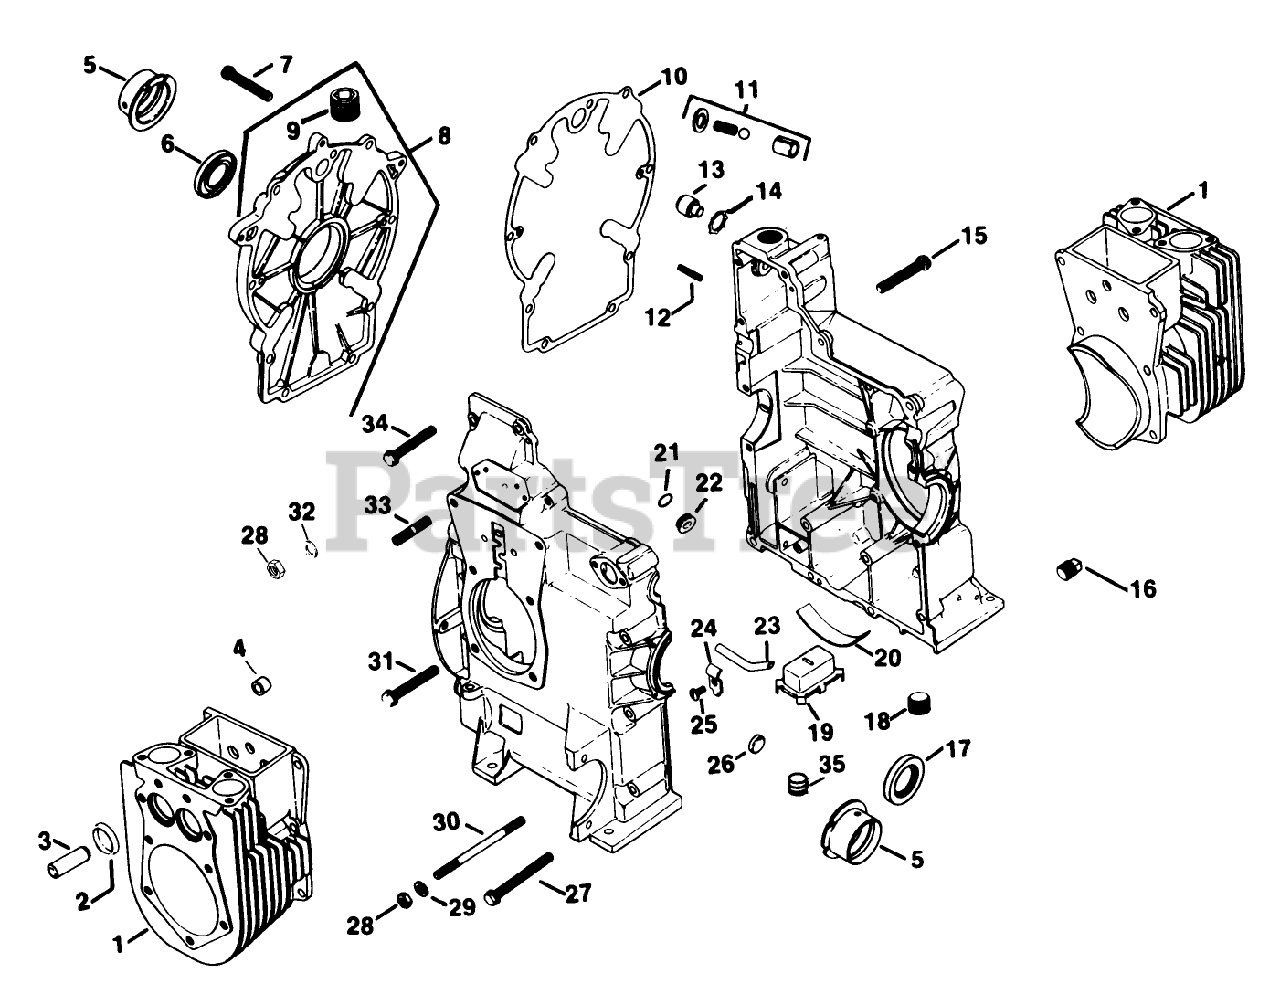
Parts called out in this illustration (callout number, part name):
1	Kit-Cylinder Barrel
2	Insert
3	Guide-Valve
4	Bushing, Locating
5	Bearing-Sleeve
6	Seal-RearOil
7	Screw-Wash Head
8	Kit-Rear Closure Plate
9	Plug
10	Gasket-Rear Closure Plate
11	Kit-Oil Relief
12	Pin-Roll
13	Shaft-Governor
14	Ring-Retaining
15	Screw-Hex Flange
16	Plug
17	Seal-ReAR Oil
18	Plug-Hex
19	Housing-Oil
20	Clip-Spring
23	Tube-Oil Pickup
25	Screw
26	Plug-Cup
27	Screw-Hex Flange
28	Nut
29	Washer-Flat
30	Stud
31	Screw-Hex Flange
32	Washer-Flat
34	Screw-Hex Flange
35	Plug-Pip Hex Ctsk
